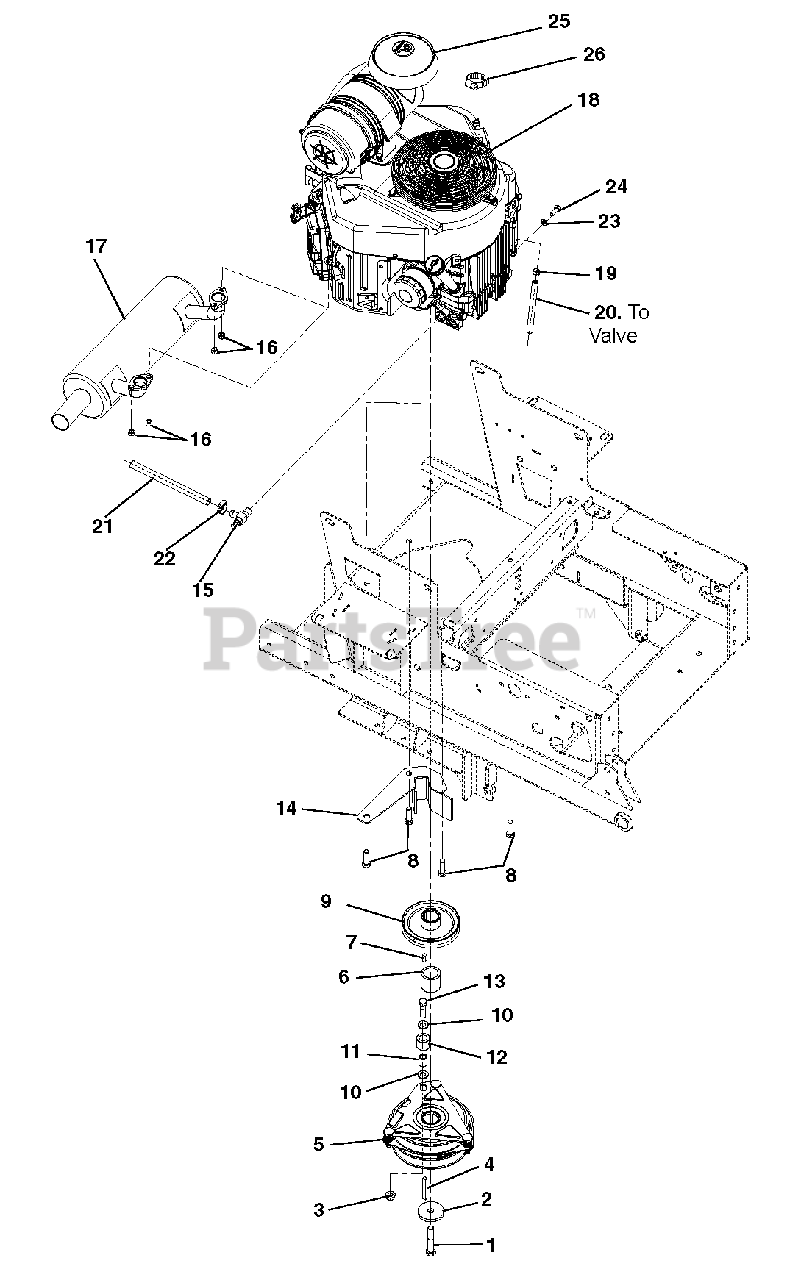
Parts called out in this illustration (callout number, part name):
1	Bolt, Hex .44-20 x 2.50 Grade 5
2	Washer, Flat-Steel .469 x 2.00 x .25
3	Nut, Locking-Top-Flange .38-16
4	Key .25 x .25 x 2.25
5	Clutch, Ogura GT2.5-FE02
6	Spacer, 1.125 x 1.50 x 1.40
7	Key, Square .25 x .625 x .25 SAE 8630 OR SAE 1035
8	Bolt, Hex .38-16 x 1.25 FTH Grade 5
9	Sheave, 4.831 x 1.127
10	Washer, Flat-Steel .406 x .812 x .065
11	Bushing, Sleeve .407 x .625 x .813 Steel
12	Bumper, Rubber .62 x 1.0 x .88 LG Engine
13	Bolt, Hex .38-16 x 1.50 Grade 5
14	100I Clutch Stop Weldment
15	Drain, .50 Oil
16	Nut, Locking-Top M8-1.25
17	Muffler, Kawasaki Fixed
18	Engine, Kawasaki FX691 (24HP) (076, 077)
19	Clamp, Fuel Line
20	Hose, .25 Low-PERM Bulk Gas
21	Tube, Oil Drain 8" Clear Vinyl
22	Clamp, .88 Diameter Hose
23	Washer, Locking .31 x .078 Regular
24	Bolt, Hex M8-1.25 x 20
25	Cap, Air Cleaner Rain
26	Clamp, Hose 2.75 Dia. Worm
